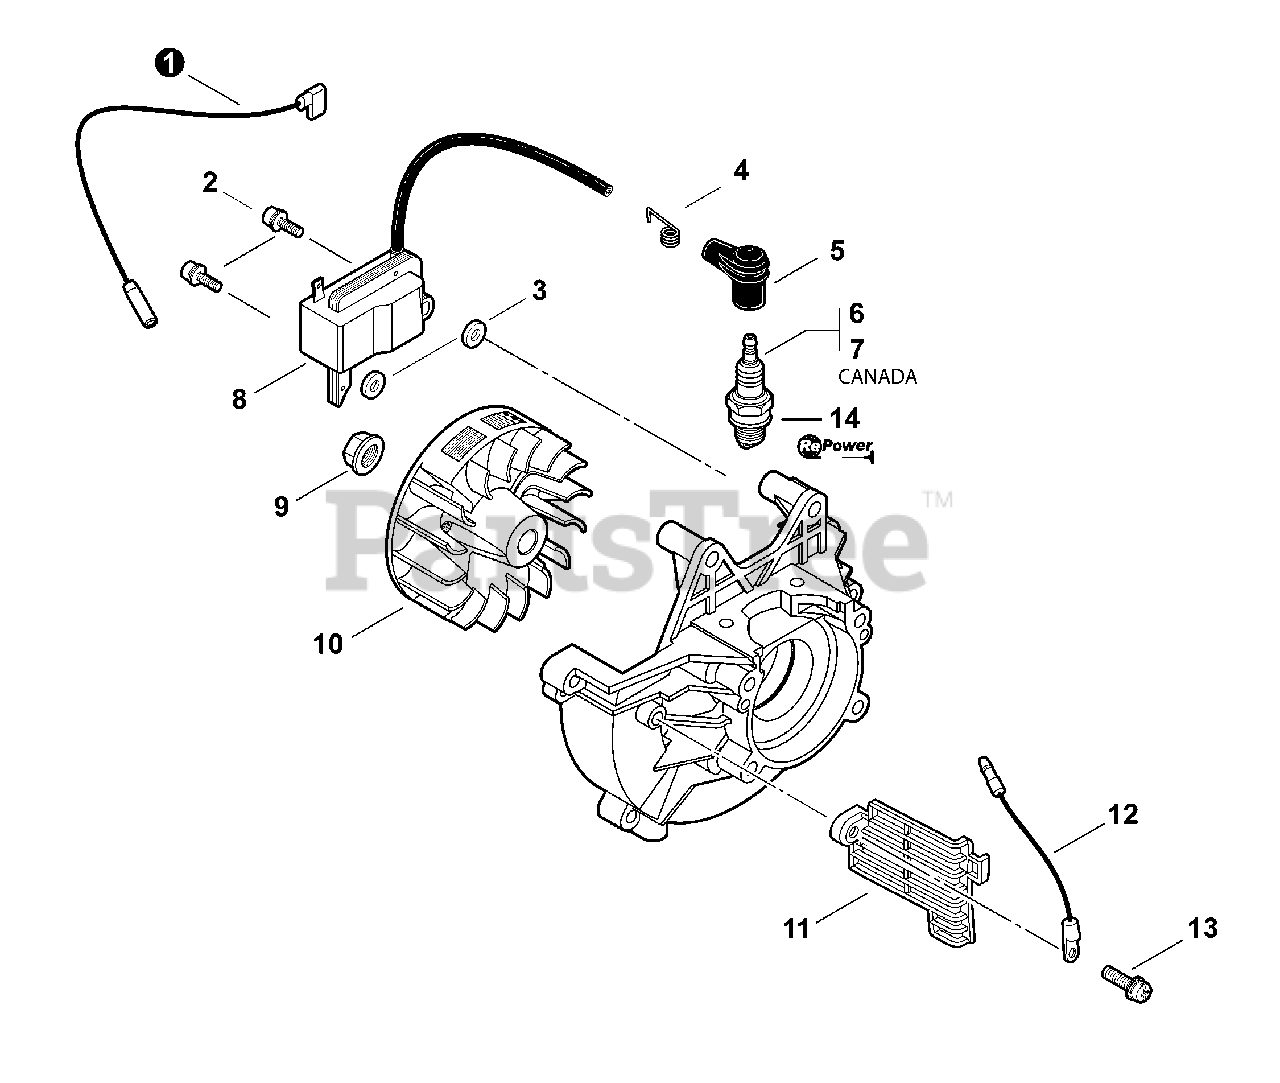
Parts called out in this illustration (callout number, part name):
1	LEAD - IGNITION
2	SCREW - 5×20
4	TERMINAL, SPARK PLUG CAP
5	CAP, SPARK PLUG
6	SPARK PLUG -- BPM8Y
7	SPARK PLUG -- BPMR8Y
8	COIL, IGNITION
9	NUT - 8 -- FLANGE
10	FLYWHEEL
11	SHIELD, DEBRIS
12	LEAD - GROUND
13	SCREW - 5×10
14	TUNE-UP KIT - REPOWER
